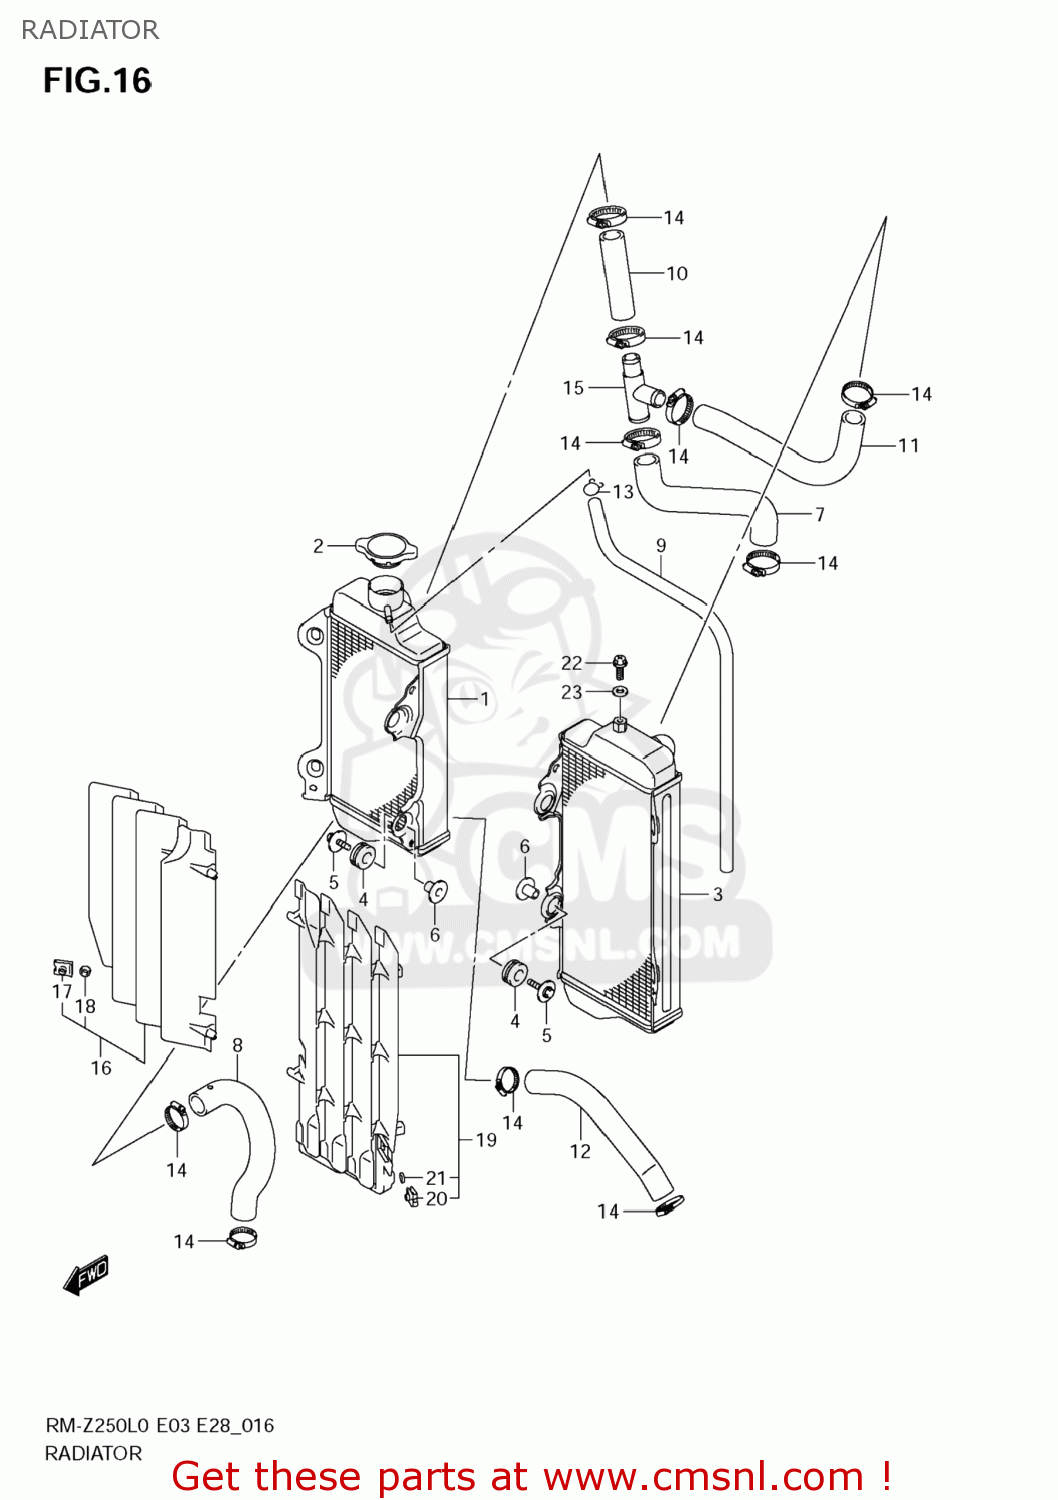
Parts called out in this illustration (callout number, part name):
1	RADIATOR COMP,
2	CAP COMP,RADIATOR
3	RADIATOR COMP,
4	CUSHION,RADIATOR LWR
5	BOLT(6X25)
6	SPACER(6.5X10.5X14.1)
7	HOSE,RADIATOR INLET NO.1
8	HOSE,RADIATOR OUTLET
9	HOSE(6X8X700)
10	HOSE,RADIATOR INLET NO.2
11	HOSE,RADIATOR INLET NO.3
12	HOSE,RADIATOR JOINT LWR
13	CLIP
14	CLAMP
15	JOINT,RADIATOR HOSE
16	LOUVER,RADIATOR,R
17	NUT
18	SPACER(6.2X10X2.2)
19	LOUVER,RADIATOR,L
20	NUT
21	SPACER(6.2X10X2.2)
22	UNION BOLT,AIR VENT
23	GASKET(6.4X11.5X0.8) (NAS)
